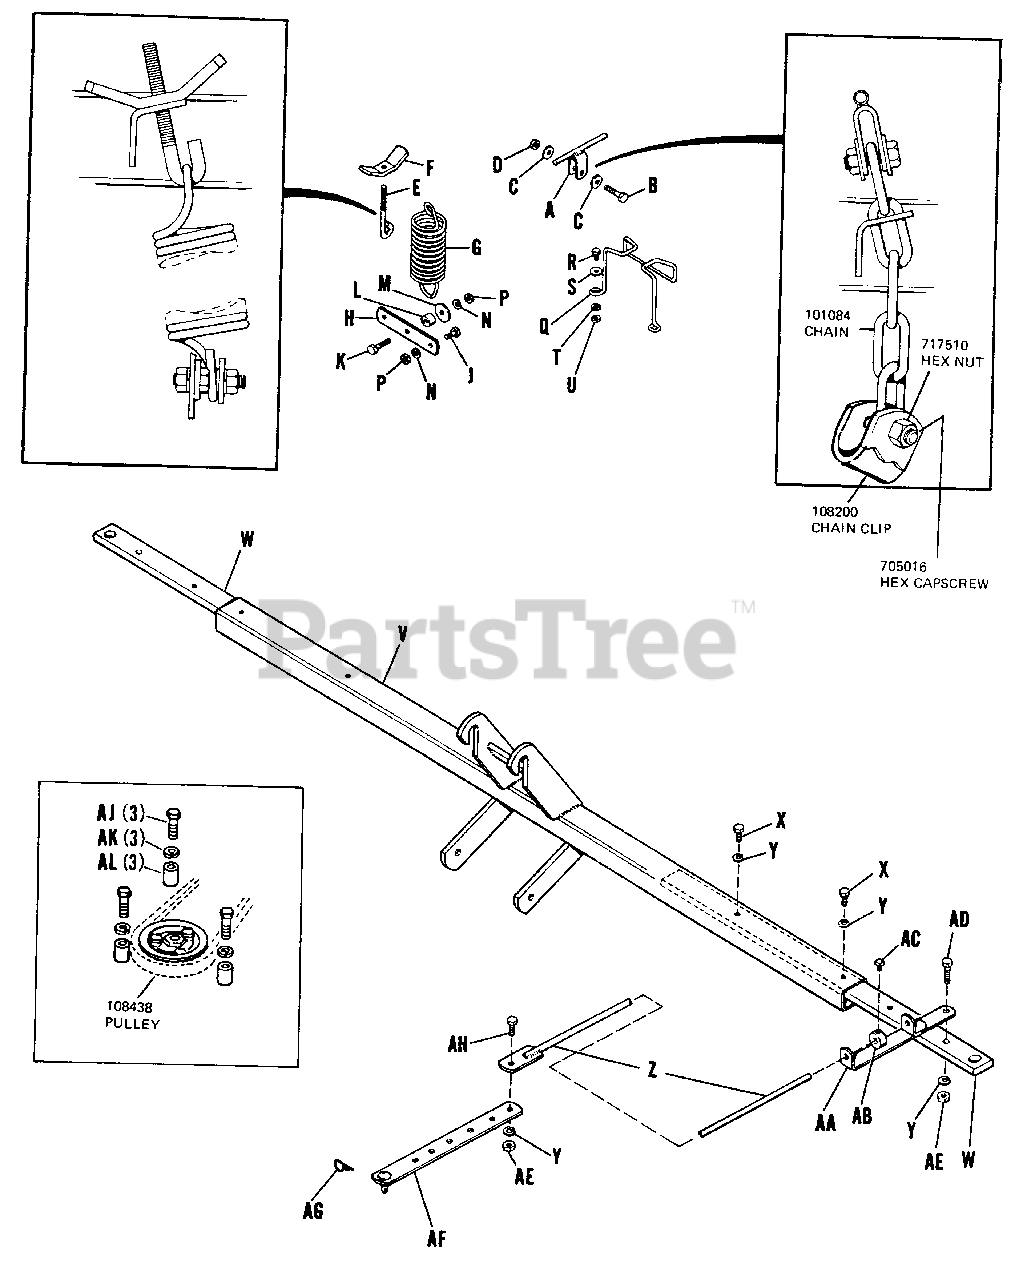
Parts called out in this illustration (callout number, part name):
A	Lift Handle Assembly
B	Hex Capscrew 5/16-18 x 1-1/4" lg.
C	Plain Washer 5/16"
D	Hex Nut Full Lock 5/16-18
E	Hook Bolt (Spring)
F	NUT, Wing, 5/16-18
H	Spring Bar
J	Hex Capscrew 5/16-18 x 5/8" lg.
K	Hex Capscrew 5/16-18 x 1-1/4" lg.
N	Lock Washer
P	Hex Nut Full
Q	Belt Stop
R	Hex Capscrew 1/4-20 x 1" lg.
S	Plain Washer 1/4"
T	Lock washer 1/4"
U	Hex Nut Full 1/4-20
V	Draw Bar Assembly
W	Hitch Bar (Mower)
X	Hex Capscrew 3/8-16 x 3/4" lg.
Y	Lock Washer 3/8"
Z	Rod Assembly
AA	Rod Guide Assembly
AB	Set Collar
AC	Set Screw 1/4-20 x 3/8" lg.
AD	Hex Capscrew 3/8-16-1-1/4" lg.
AE	Hex Nut Full 3/8-16
AF	Bar Adjusting Assembly
AG	Spring Clip
AH	Hex Capscrew 3/8-16 x 7/8" lg.
AJ	Hex Capscrew 5/16 x 2" lg.
AK	Lockwasher 5/16"
